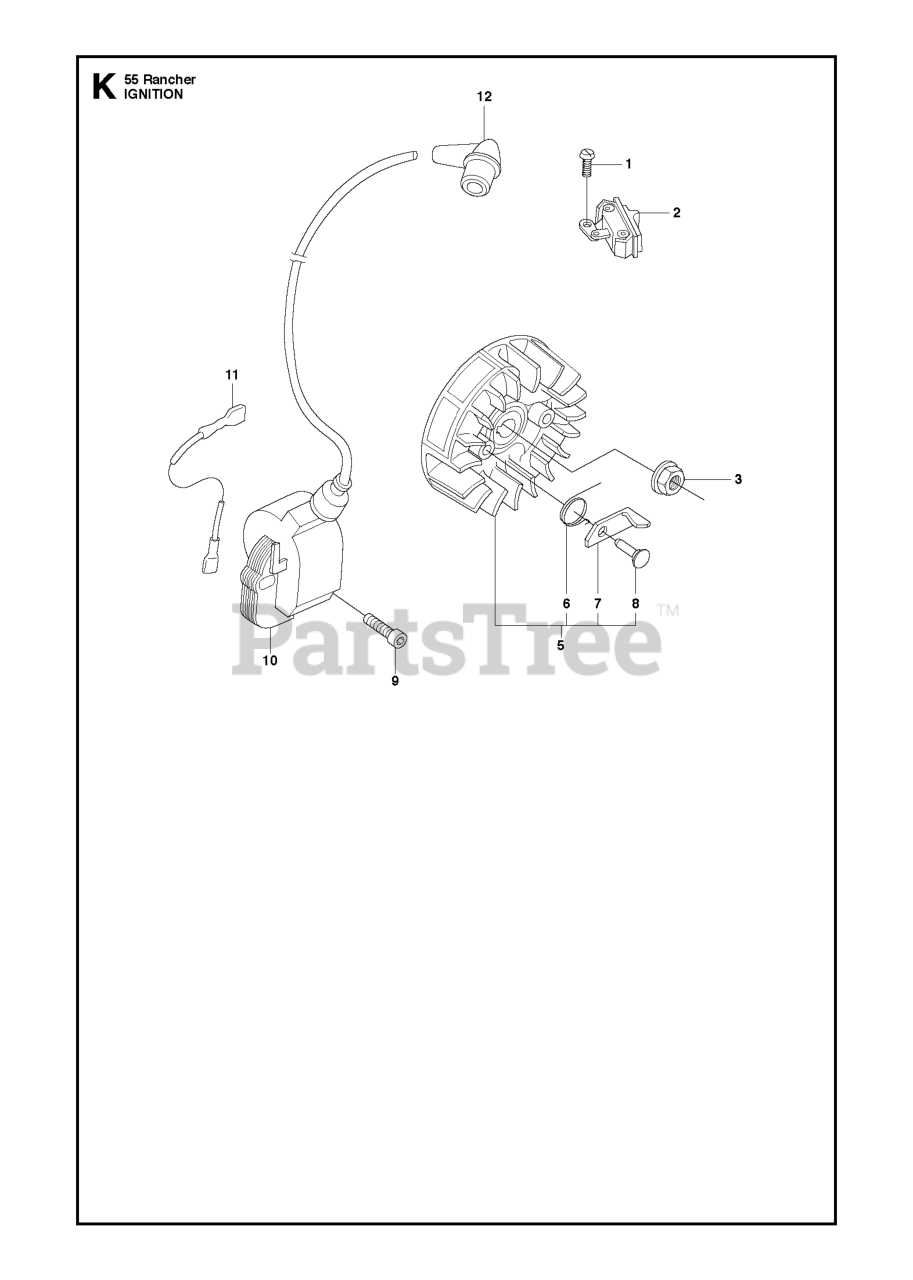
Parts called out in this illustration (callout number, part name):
2	SWITCH ON/OFF
3	NUT W/ WASHER
6	%SPRING, STARTER CATCH
10	IGNITION MODULE
12	SPARK PLUG CONN. KIT
